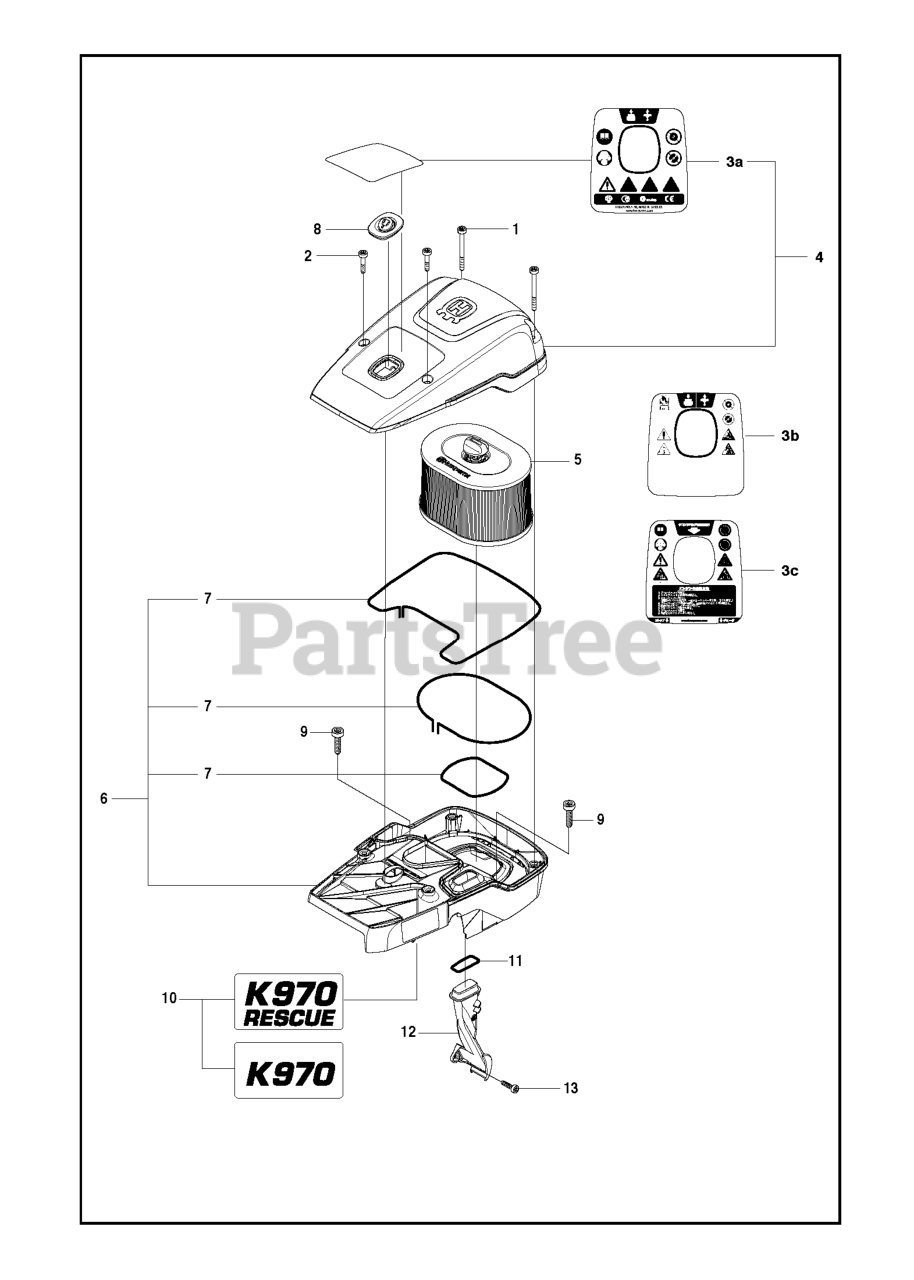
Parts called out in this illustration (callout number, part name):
2	SCREW ITXSCM
4	FILTER COVER ASSY W DECAL
5	AIR FILTER
6	CYLINDER COVER ASSY
7	SEALING 700MM
8	PLUG TOPP DK
10	DECAL CYLINDER COVER
12	AIR NOZZLE
